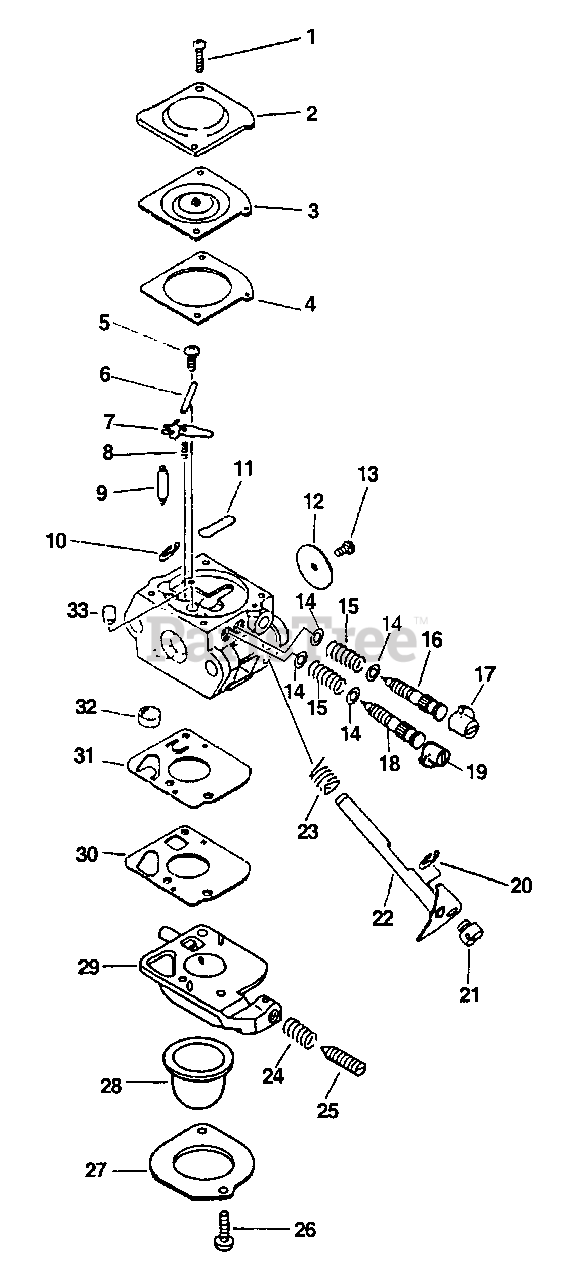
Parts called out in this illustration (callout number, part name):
2	COVER, METERING
3	DIAPHRAGM, METERING
4	GASKET, METERING
5	SCREW, METERING LEVER PIN
6	PIN, METERING LEVER
7	LEVER, METERING
8	SPRING, METERING LEVER
9	VALVE, NEEDLE
10	RING, RETAINING
11	PLUG, WELCH
12	VALVE, THROTTLE
16	NEEDLE - LOW SPEED
17	CAP, LIMITER
18	NEEDLE - HIGH SPEED
19	CAP, LIMITER
20	RING, RETAINING
22	SHAFT, THROTTLE
23	SPRING, RETURN
24	SPRING, IDLE ADJUST
25	SCREW, IDLE ADJUST
26	SCREW, RETAINER
27	RETAINER, PURGE BULB
28	BULB, PURGE
29	BASE, PURGE
30	GASKET, PUMP
31	DIAPHRAGM, PUMP
32	STRAINER
33	NOZZLE, CHECK VALVE
